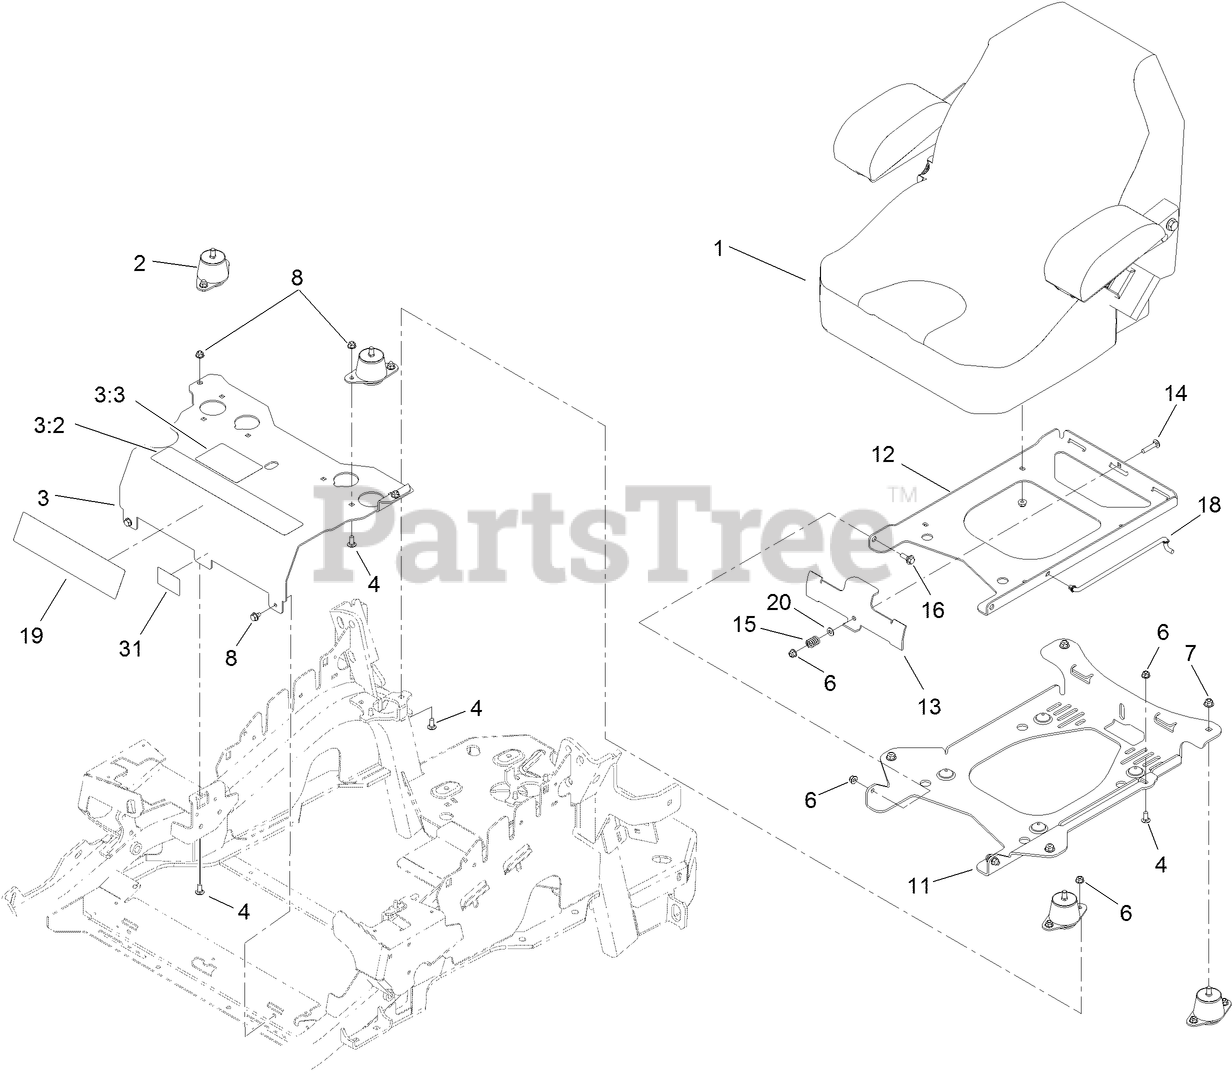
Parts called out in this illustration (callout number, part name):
1	SEAT-STANDARD
2	ISOLATOR-SEAT
3	MOUNT-SEAT
3:2	DECAL-CONSOLE
3:3	DECAL-SERVICE AID
4	SCREW-CARR
6	NUT-HF, NI
7	NUT-HF, NI
8	SCREW
11	PLATE-TILT, SEAT SUPPORT
12	PLATE-FRAME, SEAT
13	PLATE-LATCH, SEAT
14	BOLT-CARR
15	SPRING-COMPRESSION
16	SCREW-SHOULDER
18	ROD-PROP
20	WASHER-PLAIN
31	DECAL-PROPANE
